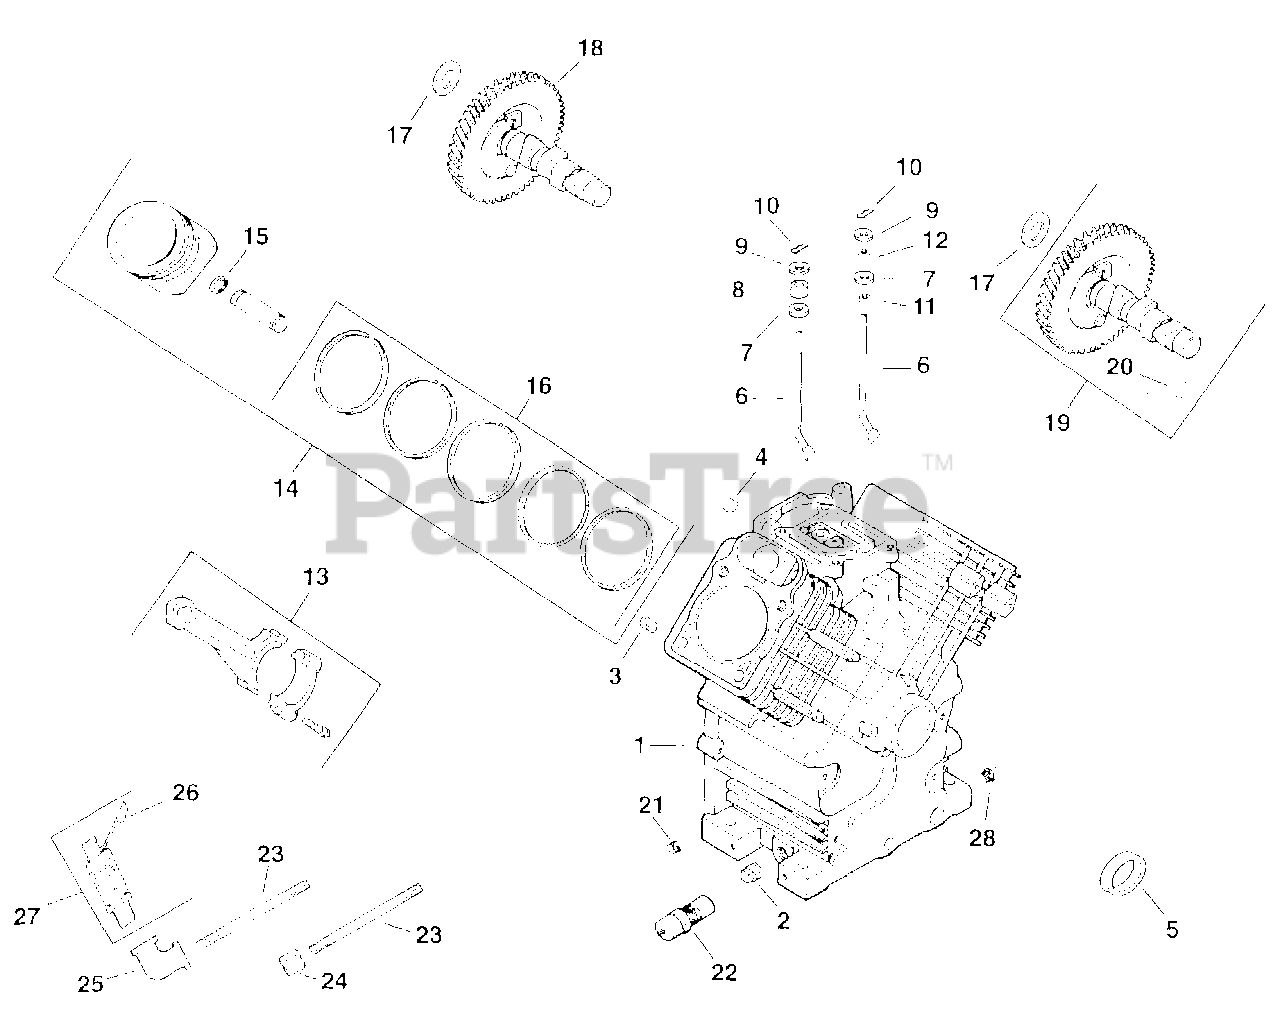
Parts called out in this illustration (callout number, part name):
1	CRANKCASE
4	PLUG, CUP
5	SEAL, OIL FRONT-USE 24 032 19-S
6	SHAFT, GOVERNOR CROSS - (#DSC)
7	WASHER, FLAT 1/4"
8	SEAL, GOVERNOR CROSS SHAFT
13	ROD, CONNECTING ASSY STD-USE 24 067 28-S
13	ROD,CONNECT ASSY.25 U/S-USE 24 067 17-S
14	PISTON W/RINGS (STYLE A)(STD) USE 24 874 17-S PISTON
14	PISTON W/RINGS (STYLE A)(.25) USE 24 874 18-S PISTON
14	PISTON W/RINGS (STYLE A)(.50) USE 24 874 19-S PISTON
15	RETAINER, PISTON PIN
16	RING SET-USE 24 108 24-S
16	RING SET-USE 24 108 13-S
17	SHIM, CAMSHAFT (WHITE .028")
17	SHIM, CAMSHAFT (BLUE .03")
17	SHIM, CAMSHAFT (RED .032")
17	SHIM, CAMSHAFT (YELLOW .034")
17	SHIM, CAMSHAFT (GREEN .036")
17	SHIM, CAMSHAFT (GRAY .038")
17	SHIM, CAMSHAFT (BLACK .04")
18	KIT, CAMSHAFT
28	PLUG, HD PIPE 3/8"
